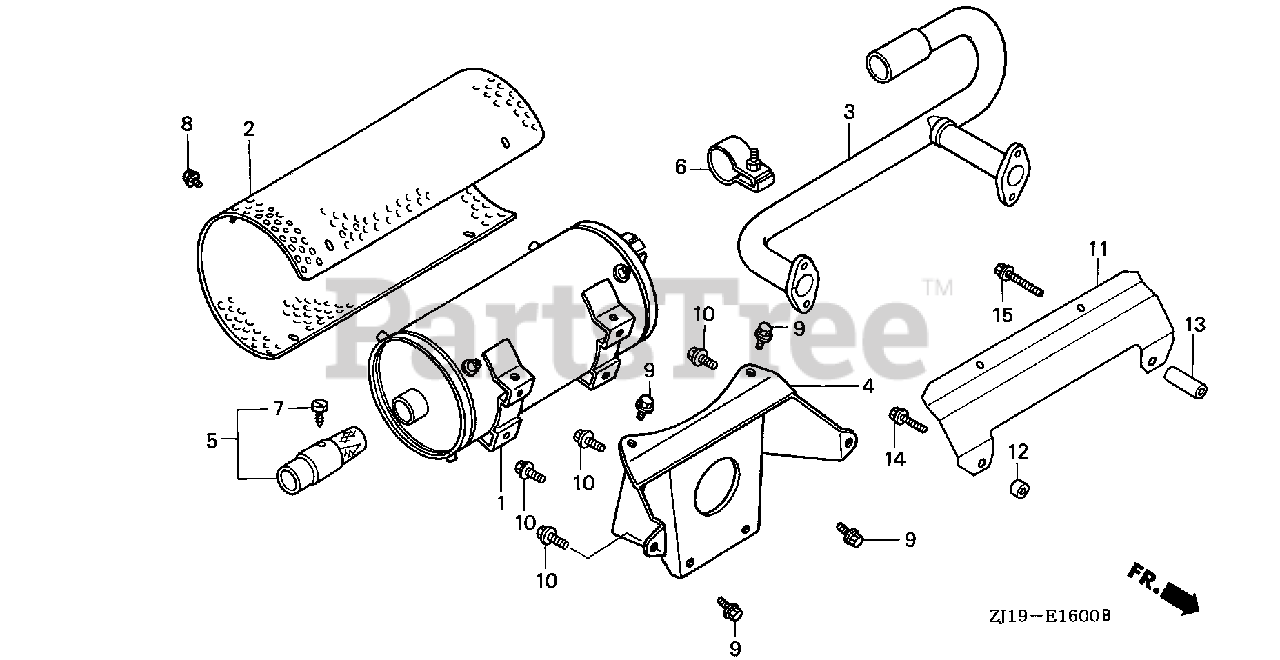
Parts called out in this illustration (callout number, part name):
1	MUFFLER COMP. (HIGH)
2	PROTECTOR, MUFFLER (HIGH)
3	PIPE COMP., EX. (HIGH-R)
4	STAY, MUFFLER (HIGH)
5	ARRESTER, SPARK
6	BAND ASSY.
7	SCREW (NELSON)
8	BOLT, FLANGE (6X8)
9	BOLT, FLANGE (8X14)
10	BOLT, FLANGE (8X20)
11	GUARD, HEAT
12	COLLAR, MUFFLER MOUNTING
13	COLLAR, ENGINE MOUNTING
14	BOLT, FLANGE (8X28)
15	BOLT, FLANGE (8X45)
